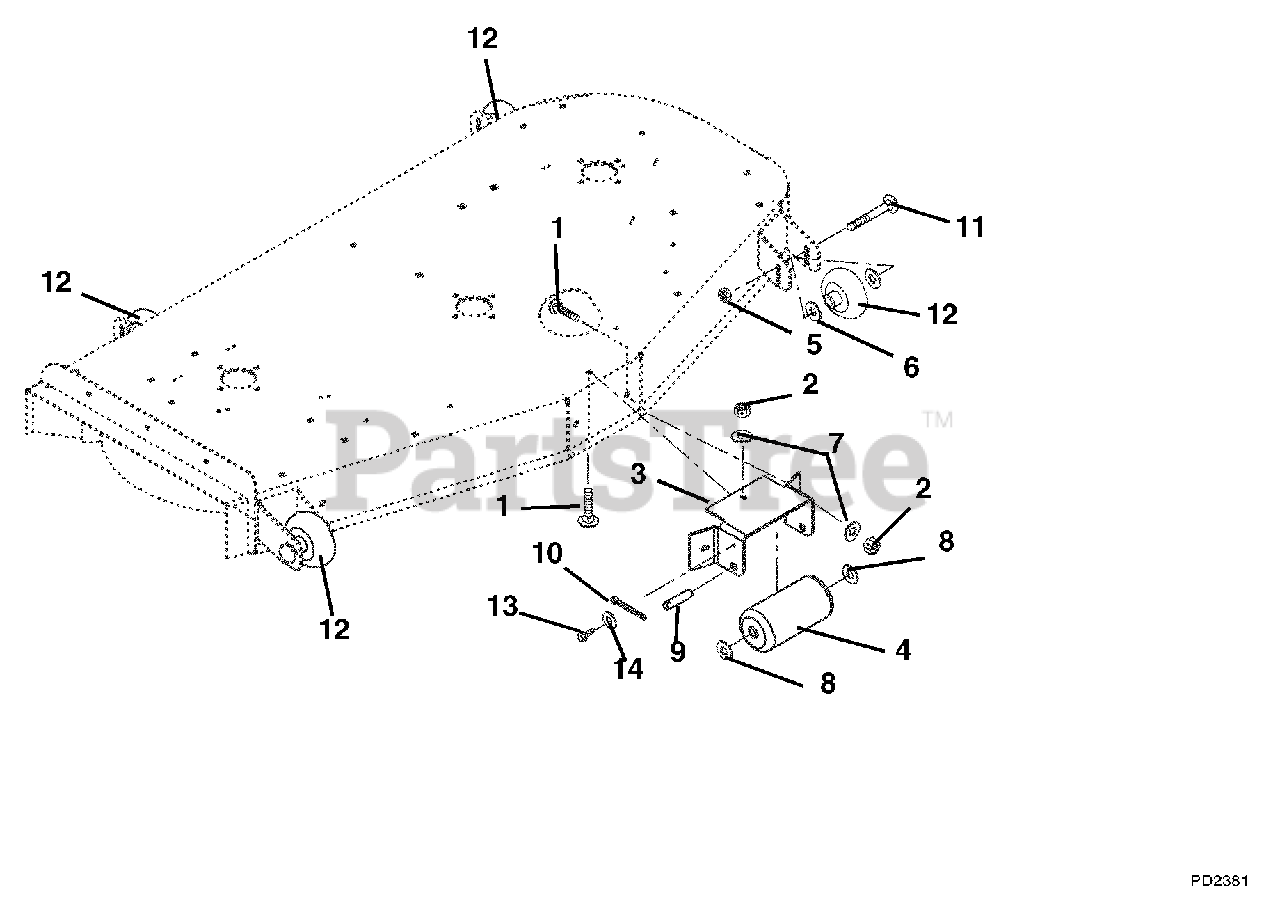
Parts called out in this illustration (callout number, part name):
1	Bolt-Round Head Square Neck .38-16 x 1.00 Grade 5
2	Nut-Locking-Nylon .38-16
3	Bracket, Anti-Scalp Roller
5	Nut-Locking-Nylon .50-13
6	Washer-Flat-Steel .531 x 1.06 x .095
7	Washer-Flat-Steel .406 x .812 x .065
8	Washer-Flat-Steel .656 x 1.31 x .095
10	Pin-Cotter .25 x 2.0
11	Bolt-Round Head Square Neck .50-13 x 5.00 Grade 2
12	Wheel, 3 x 5
13	Screw-Self Tapping .25-20 x .50 x Hex Washer Head
14	Washer-Flat-Steel .281 x .62 x .065
